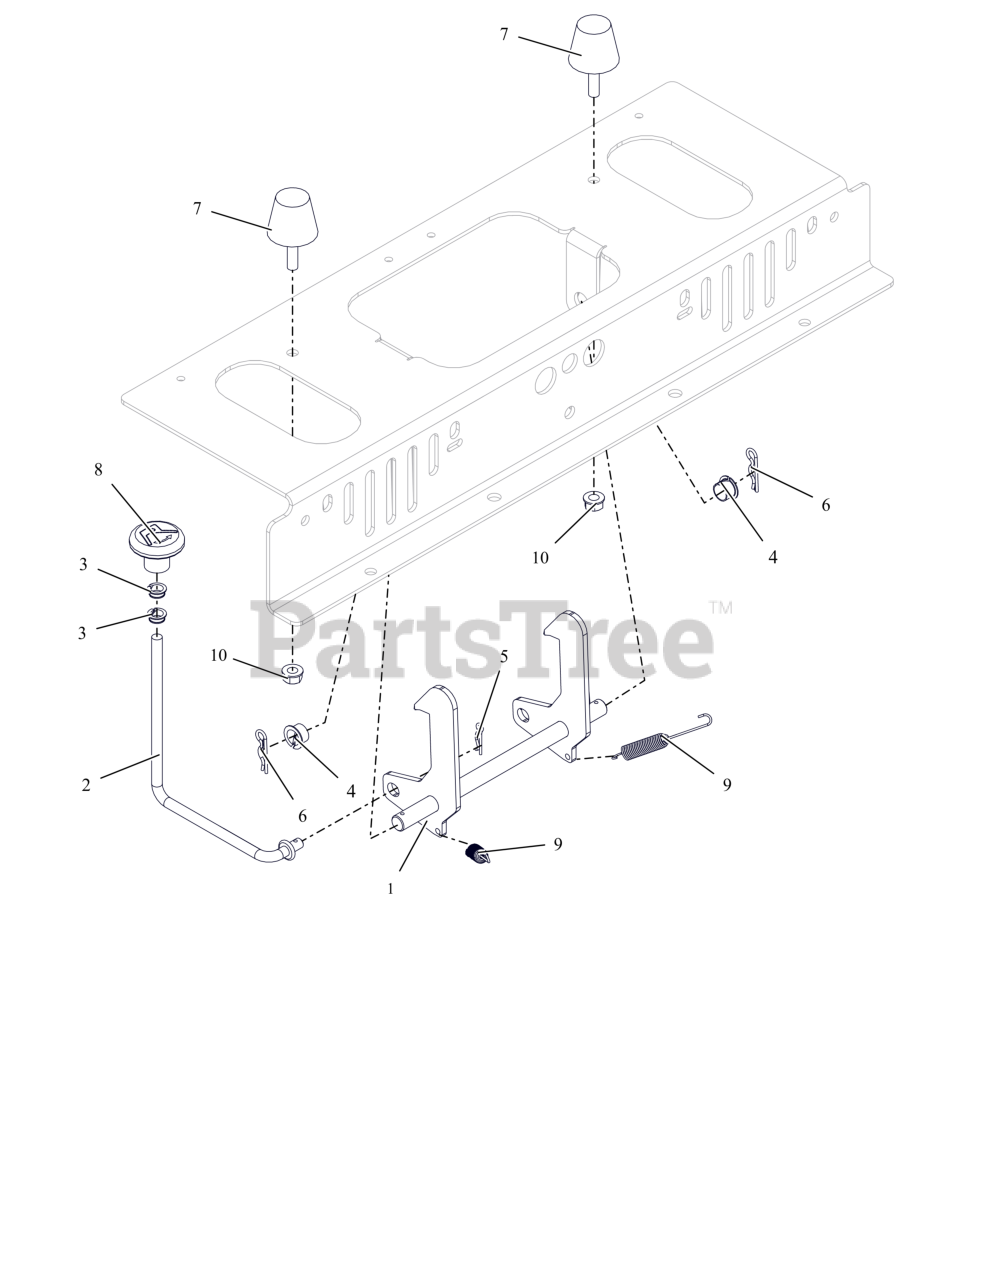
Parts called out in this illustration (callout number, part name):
1	SEAT LATCH WLDMT - LOW FILM
2	LINKAGE, SEAT RELEASE
3	BUSHING, POLYLINER-.38 SNAPIN
4	BUSHING, POLYLINER-.50 SPLIT
5	PIN, HAIR #225 .072X1.09
6	PIN, HAIR-INT .08X.38X1.42 ZCC
7	BUMPER,STUD MOUNTED CONE SHAPE
8	KNOB, PUSH/PULL
9	SG-TENS .043X.44X3.31 WLD 5.8
10	NUT,SPNLK-FLG .31-18 G5 ZCC
